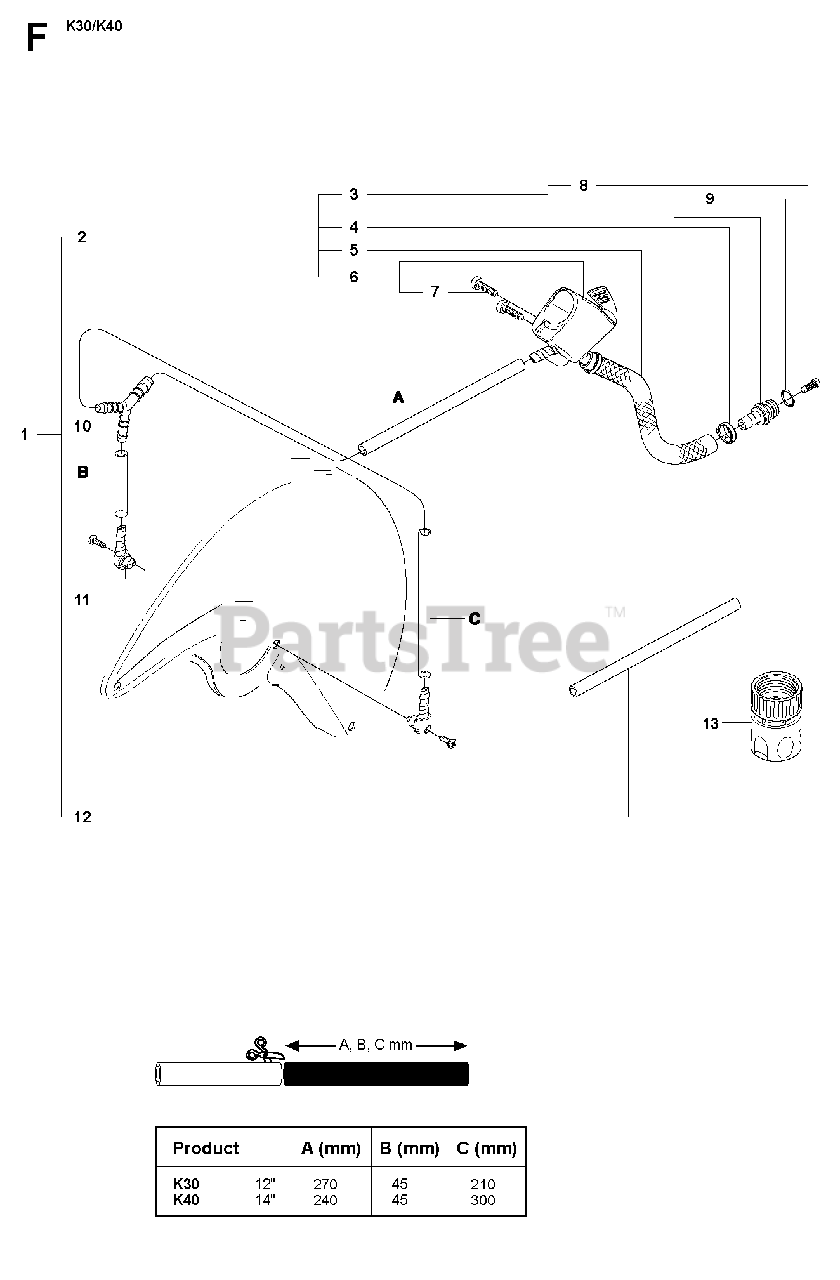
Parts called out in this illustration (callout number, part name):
2	VALVE ASSY
4	HOSE CLAMP
5	HOSEL=230mm
6	VALVE ASSYIncl. 7
9	O-RING
12	HOSE
13	COUPLER
